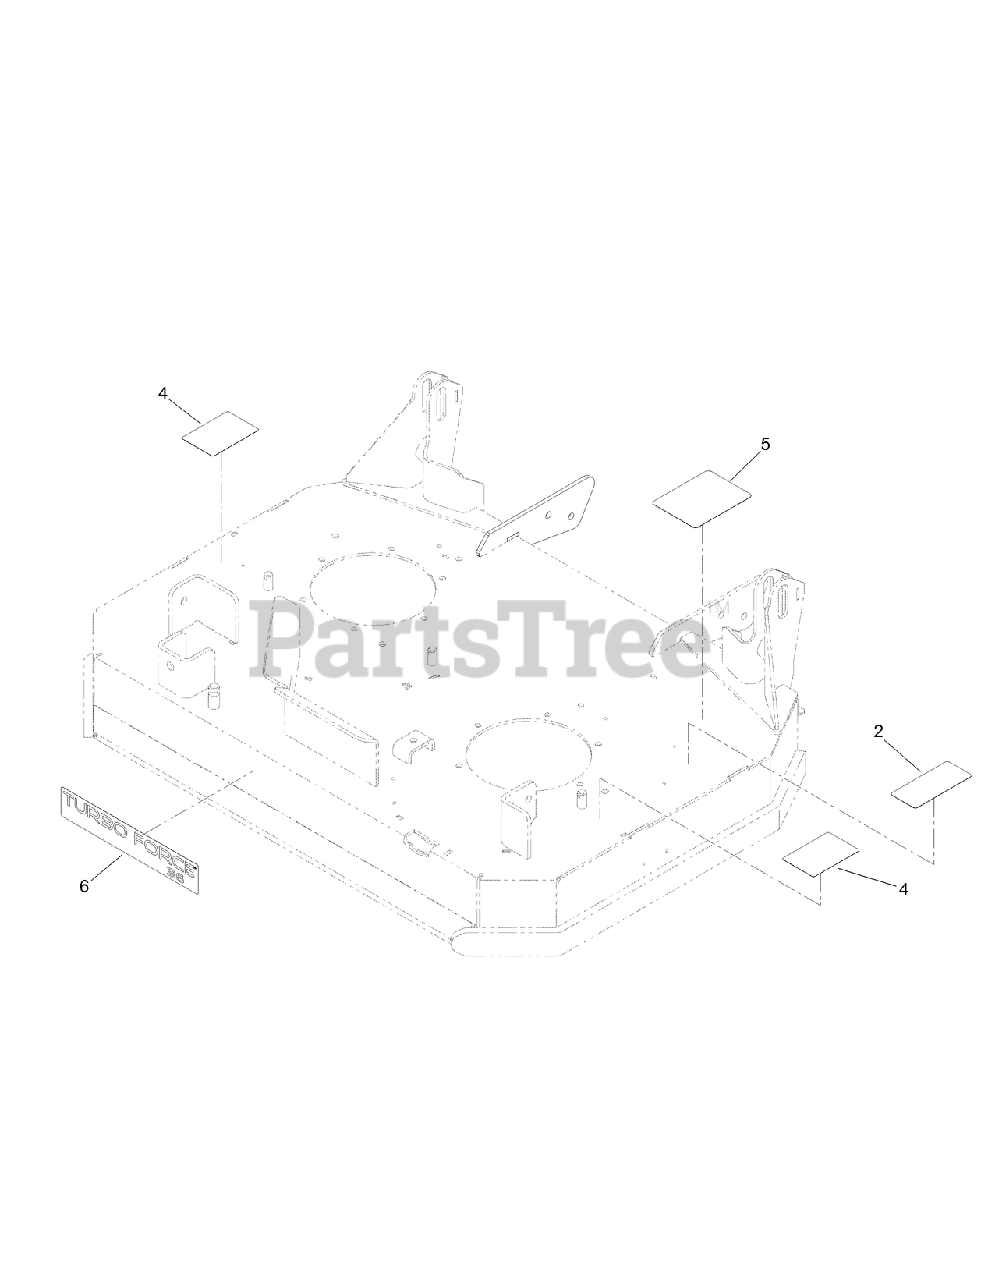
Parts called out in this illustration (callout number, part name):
2	DECAL-TORQUE, BLADE BOLT
4	DECAL-DANGER, CE
5	DECAL-BELT ROUTING
